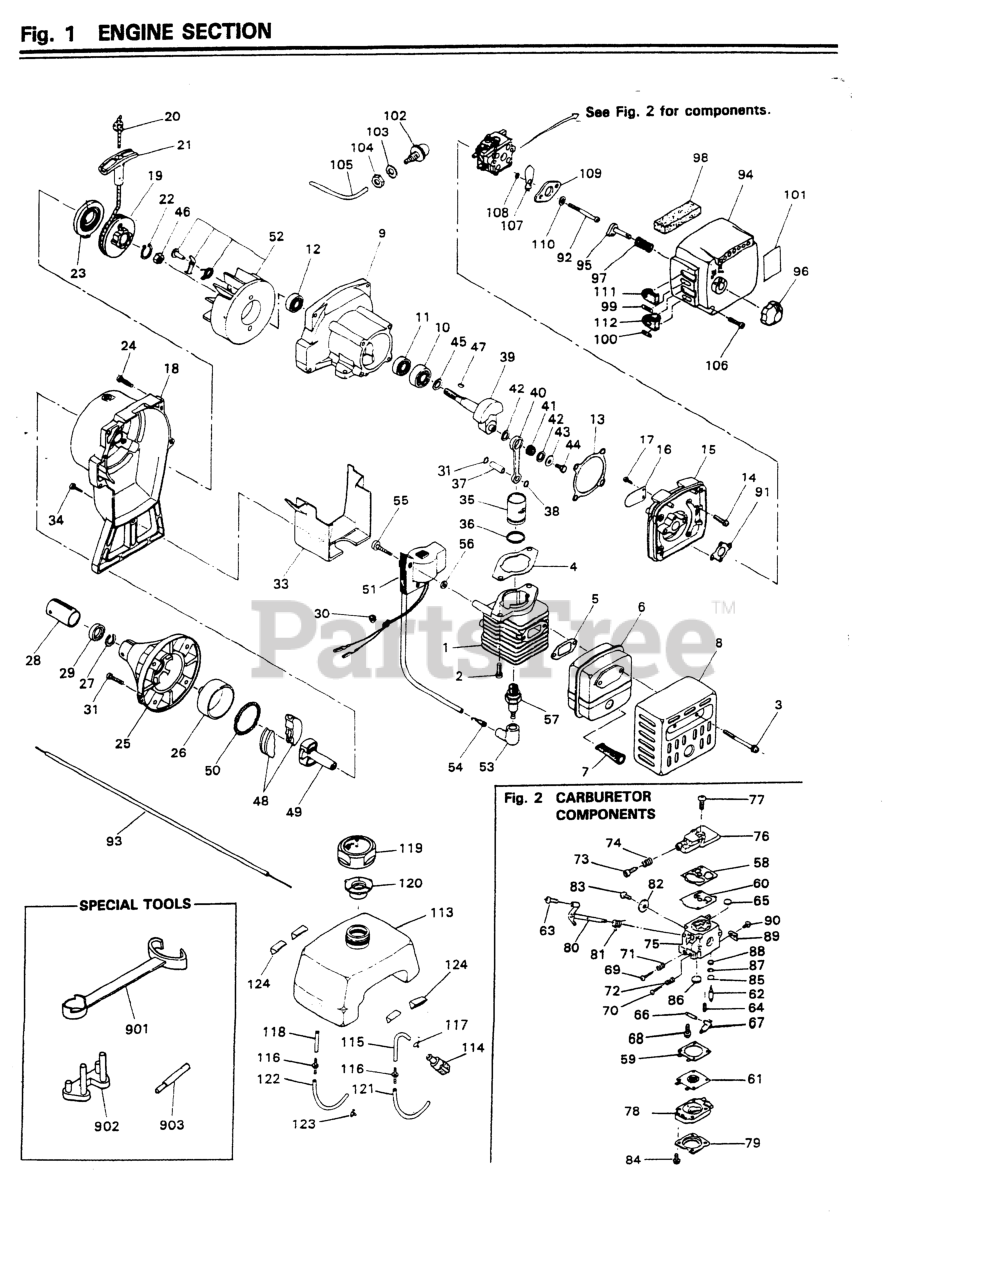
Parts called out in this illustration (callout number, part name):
2	SCREW, M6 x 16
3	SCREW, M5 X 55
4	GASKET(NO LONGER AVAILABLE)
7	ARRESTER (RPLS 5850-15140)
8	GUARD (NO LONGER AVAILABLE)
11	SEAL, OIL (NO LONGER AVAIL)
13	GASKET(NO LONGER AVAILABLE)
16	REED VALVE (NO LONGER AVAIL)
18	COVER COMPL (NLA)
19	REEL COMPLETE
21	KNOB (NLA)
22	RING, SNAP, M18 x 1.2
23	HOLDER COMPLETE
24	SCREW, M5 X 16
30	GROMMET(NO LONGER AVAILABLE)
34	SCREW (NO LONGER AVAILABLE)
38	RING, SNAP (RPLS 1101-41320)
43	WASHER (NO LONGER AVAIL)
44	BOLT (NO LONGER AVAILABLE)
45	WASHER(NO LONGER AVAILABLE)
48	SHOE (NO LONGER AVAILABLE)
50	SPRING (NO LONGER AVAILABLE)
51	MODULE(NO LONGER AVAILABLE)
53	CAP, PLUG
54	SPRING PLUG (RPLS 3310-71320)
58	KIT ONLY
59	KIT ONLY
60	KIT ONLY
61	DIAPHRAGM (USE 4810-81260)
62	KIT ONLY
64	KIT ONLY
66	PIN, METERING LEVER
67	LEVER
78	BODY (NO LONGER AVAILABLE)
79	COVER
86	PLUG WELCH
90	SCREW ASSEMBLY
91	GASKET (NO LONGER AVAILABLE)
92	SCREW, M5 x 40
94	COVER, AIR CLEANER (NLA)
95	LEVER,CHOKE(NO LONGER AVAIL)
97	SPRING (NO LONGER AVAILABLE)
98	ELEMENT (NO LONGER AVAILABLE)
99	LABEL (NO LONGER AVAILABLE)
100	LABEL (NO LONGER AVAILABLE)
102	BODY ASSY
103	WASHER (NO LONGER AVAIL)
104	NUT, PRIMER (NO LONGER AVAIL)
105	PRIMER HOSE
106	SCREW, M5 X 20
107	PLATE (NO LONGER AVAILABLE)
110	WASHER, M5x.8(RPLS 01624-20508
111	GROMMET (NO LONGER AVAILABLE)
112	GROMMET (NO LONGER AVAILABLE)
114	5500-85400 (RRLS. 1750-85300)
115	PIPE (NLA)
116	JOINT (NLA)
117	CLIP (REPLACES 2841-31280)
119	CAP COMPLETE
123	CLIP
124	CUSHION (NO LONGER AVAIL)
NI	GASKET KIT
NI	REPAIR KIT
